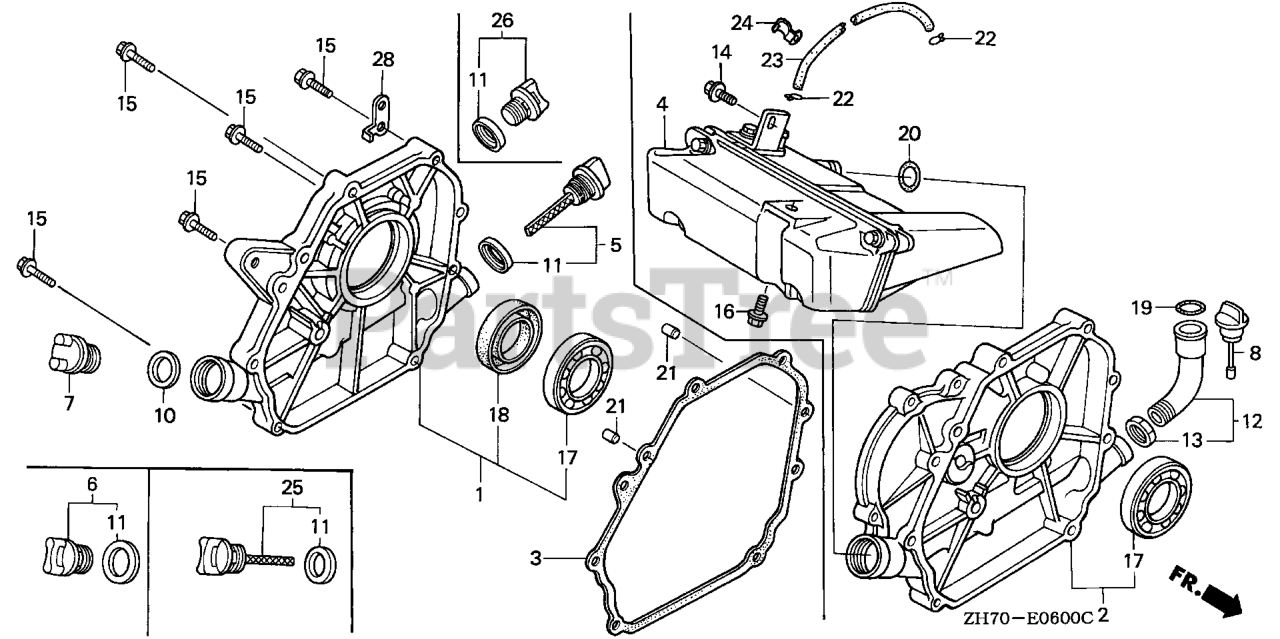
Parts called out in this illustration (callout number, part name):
1	COVER ASSY., CRANKCASE
3	GASKET, CASE COVER
5	CAP ASSY., OIL FILLER
6	CAP ASSY., OIL FILLER
11	GASKET, OIL FILLER CAP
15	BOLT, FLANGE (6X28) (CT200) Use up to Engine SN 1530314.
17	BEARING, RADIAL BALL (62/22)
18	OIL SEAL (22X41X6)
21	PIN A, DOWEL (8X14)
